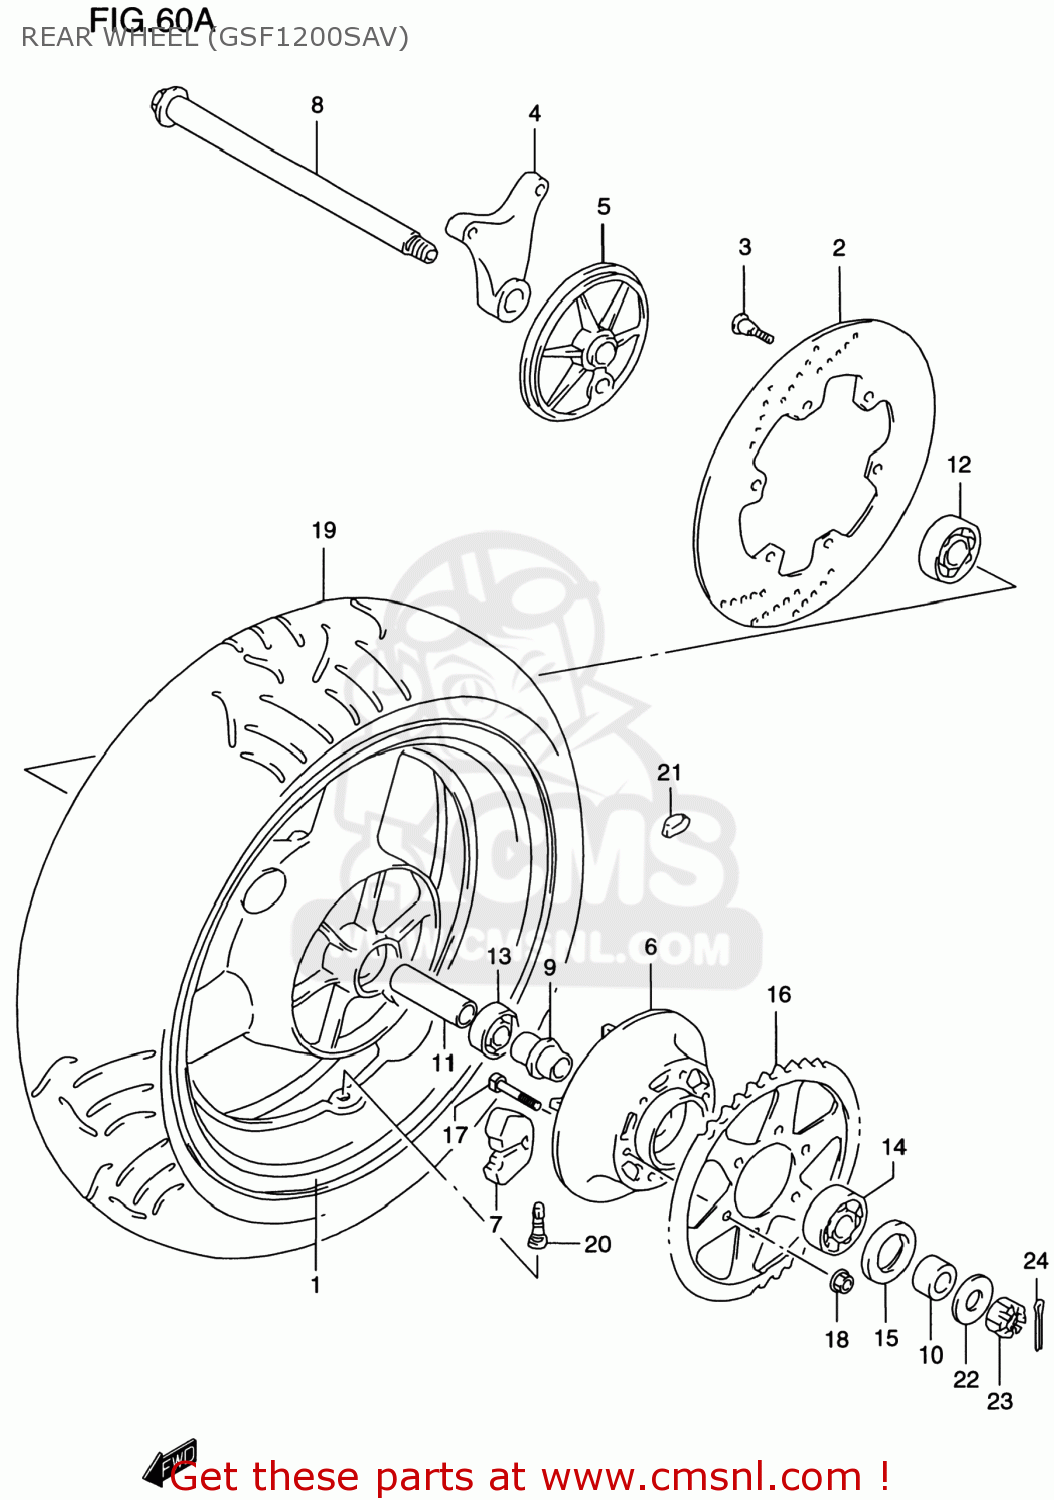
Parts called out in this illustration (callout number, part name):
1	WHEEL SET,REAR (17XMT5)
2	DISC,RR BRAKE
3	BOLT 8X33
4	BRACKET,RR CALIPER
5	PANEL,SPEED SENSOR RR
6	DRUM,RR SPROCKET
7	ABSORBER,RR HUB SHOCK
8	AXLE,RR
9	RETAINER,RR HUB BEARING
10	SPACER,RR AXLE,L
11	SPACER,RR WHEEL HUB BEARING
12	BEARING(20X47X14)
13	BEARING(20X47X14)
14	BEARING(25X62X17)
15	SEAL,OIL(35X62X8)
16	SPROCKET,RR(NT:45-530)
17	BOLT
18	NUT
19	TIRE,RR(180/55 ZR17 73W)
20	VALVE ASSY,WHEEL RIM(TR412)
21	BALANCER,WHEEL (10G)
22	WASHER(18.5X28X2.6)
23	NUT
24	PIN, COTTER
